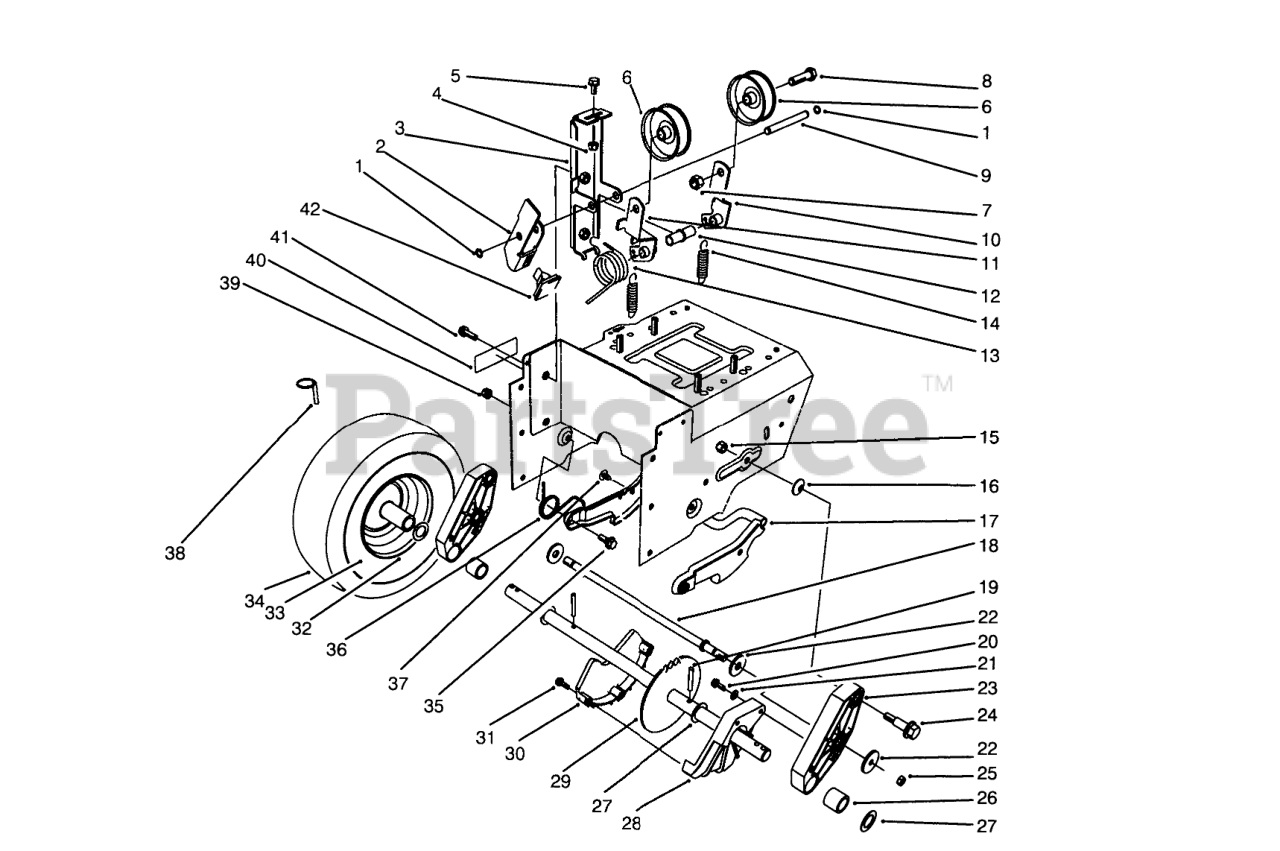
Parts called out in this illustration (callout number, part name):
1	RING-RETAINING
2	ARM-BRAKE
3	IDLER ARM BRACKET ASM
4	NUT-LOCK, NI
5	SCREW-HHF
6	PULLEY-IDLER
7	NUT-LOCK, NI
8	SCREW-HH
9	PIN-IDLER
10	ARM-IDLER, TRACTION
11	ARM-IDLER, IMPELLER
12	BUSHING-IDLER
13	SPRING-TORSION
14	SPRING-EXTENSION
15	NUT-LOCK, NI
16	WASHER-SPRING
17	Latch-Arm
18	ROD-LATCH
19	PIN-ROLL, SLOTTED
20	SCREW-HWH
21	WASHER-FLAT
22	WASHER-SUPPORT
23	Pivot Arm Assembly (Incl. Ref. # 26)
24	BOLT-SHOULDER
25	NUT-LOCK, NI
26	BUSHING-AXLE
27	WASHER-THRUST
28	GUARD-CHAIN, LH
29	AXLE ASM
30	GUARD-CHAIN, RH
31	Screw
32	WHEEL
33	TUBE-INNER
35	SCREW-SHOULDER
36	SPRING-LATCH, TORSION
37	FASTENER-PANEL
38	PIN-LYNCH
39	NUT-LOCK, NI
40	DECAL-WARNING
41	SCREW-HHF
42	PAD-BRAKE
